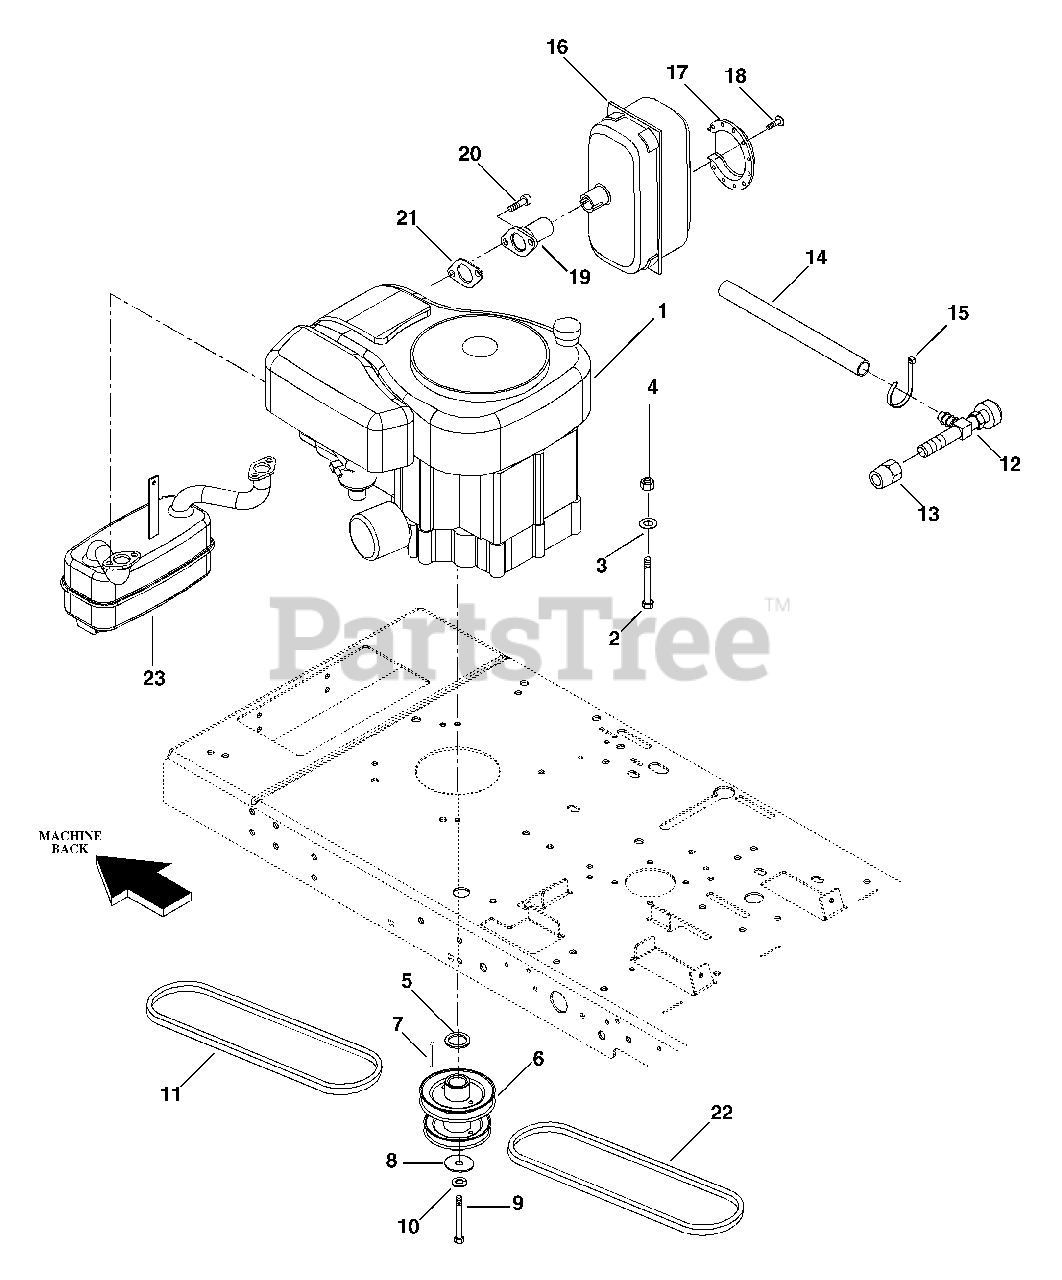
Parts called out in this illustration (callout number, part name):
1	Engine-Briggs & Stratton Intek Single 17HP
1	Engine-Briggs & Stratton Intek 20HP V Twin
2	Bolt-Hex .31-18 x 1.50 Grade 5
3	Washer-Flat-Steel .328 x 1.00 x .094
4	Nut-Locking .312-18
5	Spacer
6	Engine Sheave 4.50
7	Key-Square .25 x 2.50 x .25
8	Washer-Special .469 x 2.000 x .250
9	Bolt-Hex .44-20 x 3.00 Grade 5
10	Washer-Lock .44 x .109
11	V-Belt, Transmission Drive
12	Cock, Oil Drain
13	Adapter, Oil Drain
14	Tube Oil Drain
15	Cable Tie
16	Muffler-Briggs & Stratton 496652
17	Deflector-Briggs & Stratton 222573
18	Screw-Briggs & Stratton 93705
19	Muffler Adaptor Pipe (015)
20	Screw-Cap .31-18 x .75
21	Gasket
22	Belt-5L x 47.1 Engine to Jackshaft
23	Muffler Assembly
